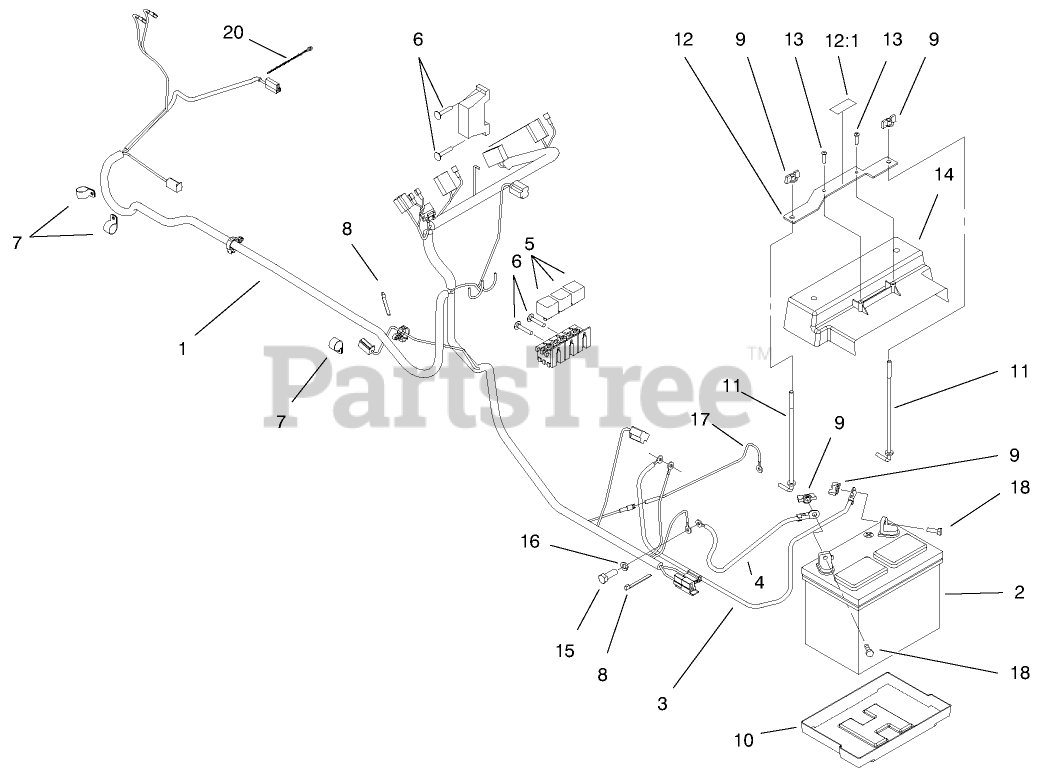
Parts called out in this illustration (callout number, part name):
3	CABLE-BATTERY, RED 27IN
4	CABLE-BATTERY
5	RELAY
6	SCREW
7	CLAMP - R
8	TIE-CABLE
9	NUT-WING
10	TRAY-BATTERY
11	HOOK-RETAIN, BATTERY
12	STRAP ASM
12:1	DECAL-SURFACE, HOT
13	SCREW-PPH
14	SHIELD-BATTERY
15	SCREW-HHF
16	WASHER-LOCK
17	HARNESS-WIRE
18	SCREW-HH
